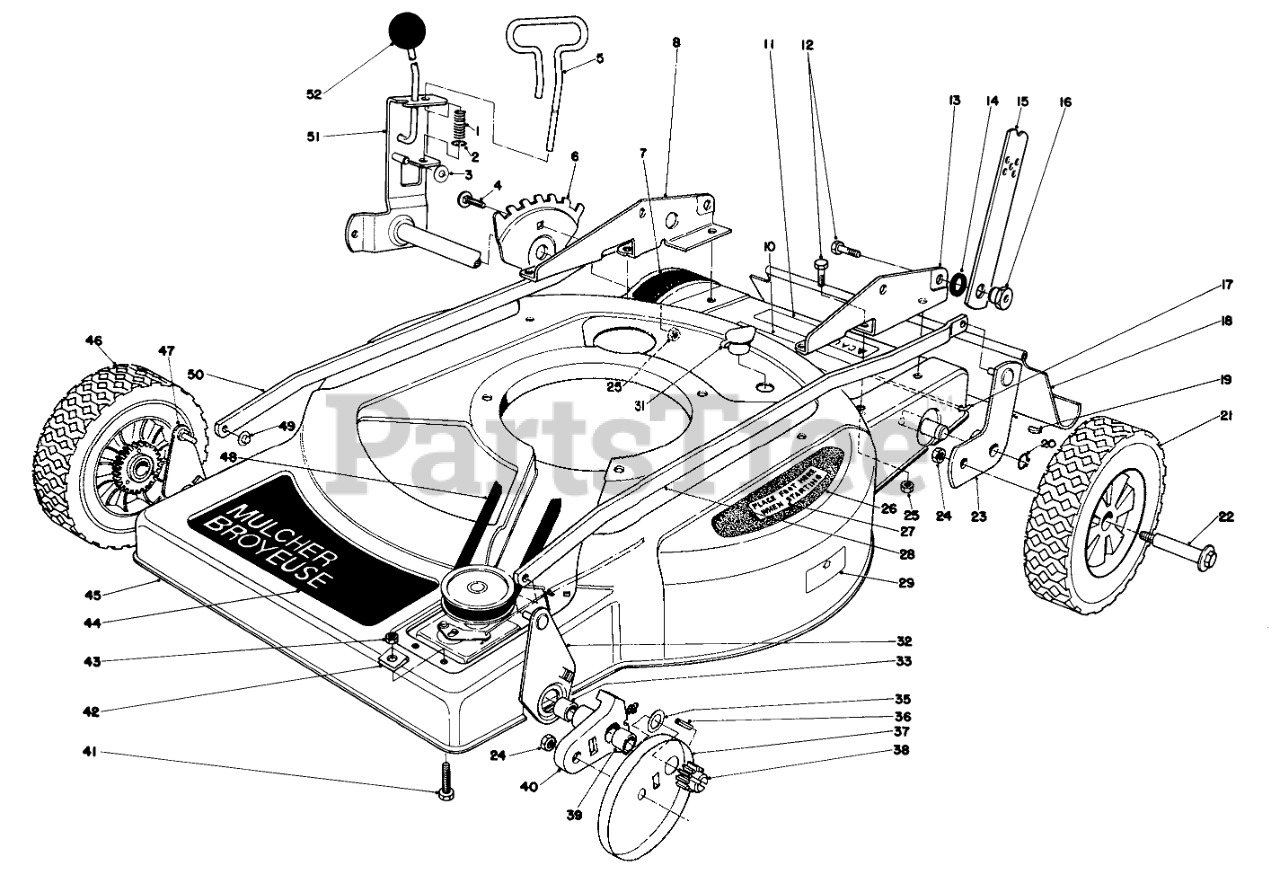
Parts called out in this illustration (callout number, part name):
1	SPRING-COMPRESSION
2	E-RING
3	WASHER-FLAT
4	Carriage Bolt
5	STOP ROD
6	HOC ADJUSTMENT PLT
7	Decal Height of Cut
8	Bracket Handle R.H.
10	Decal Caution
11	Caution Decal
12	SCREW-HH
13	Bracket-Handle R.H.
14	SPACER
15	HANDLE LATCH
16	HANDLE PIVOT NUT
17	SHIELD ROD
18	SHIELD - TRAILING
19	KEY-WOODRUFF
20	RING-RETAINING
21	WHEEL TIRE ASM 8 IN
22	BOLT-WHEEL
23	Pivot Arm
24	Nut
25	NUT-LOCK, CONE
26	PAD STEP
27	Decal Step Pad
28	Spanner Link L.H.
29	Decal Step
31	WASHOUT PLUG
32	Link Pivot Arm L.H.
33	BUSHING
35	WASHER-THRUST
36	Pin
37	WHEEL COVER
38	Pinion
39	BUSHING
40	Pivot Arm (Incl. Ref. #33 & 39)
41	SCREW
42	SPEED NUT
43	NUT-LOCK
44	Decal-Front Deck
45	Housing
46	Wheel & Tire Assembly
47	Link Pivot Arm R.H.
48	V BELT
49	NUT-SPEED
50	Spanner Link R.H.
51	Pivot Arm Bracket
